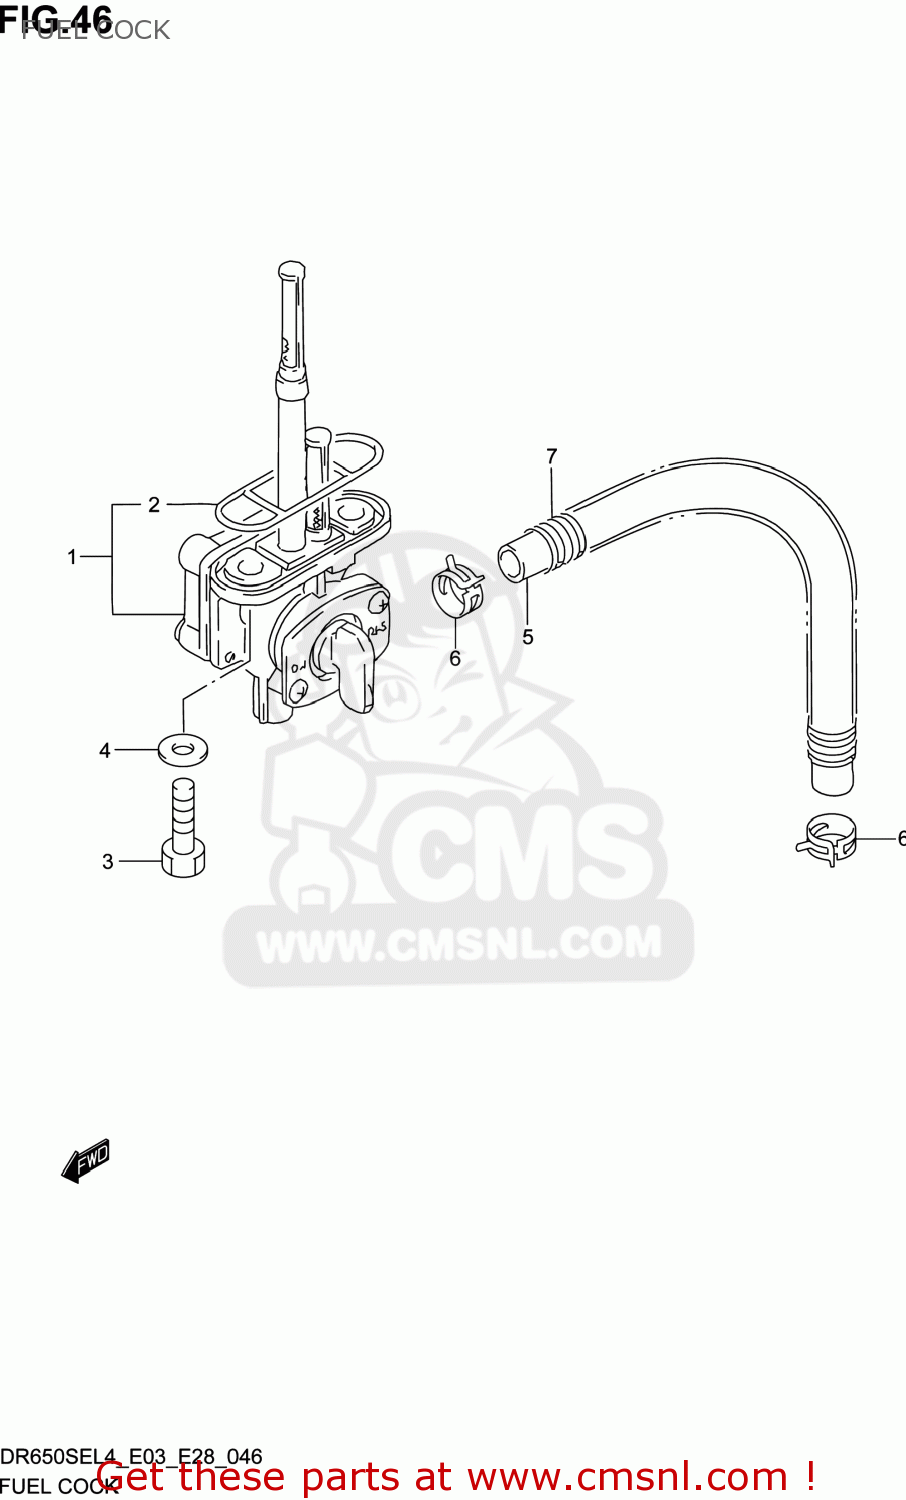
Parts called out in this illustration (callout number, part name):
1	COCK ASSY,FUEL
2	GASKET,JOINT (NAS)
3	BOLT(6X20)
4	GASKET(6.4X11.5X0.8) (NAS)
5	HOSE,FUEL
6	CLIP
7	SPRING
